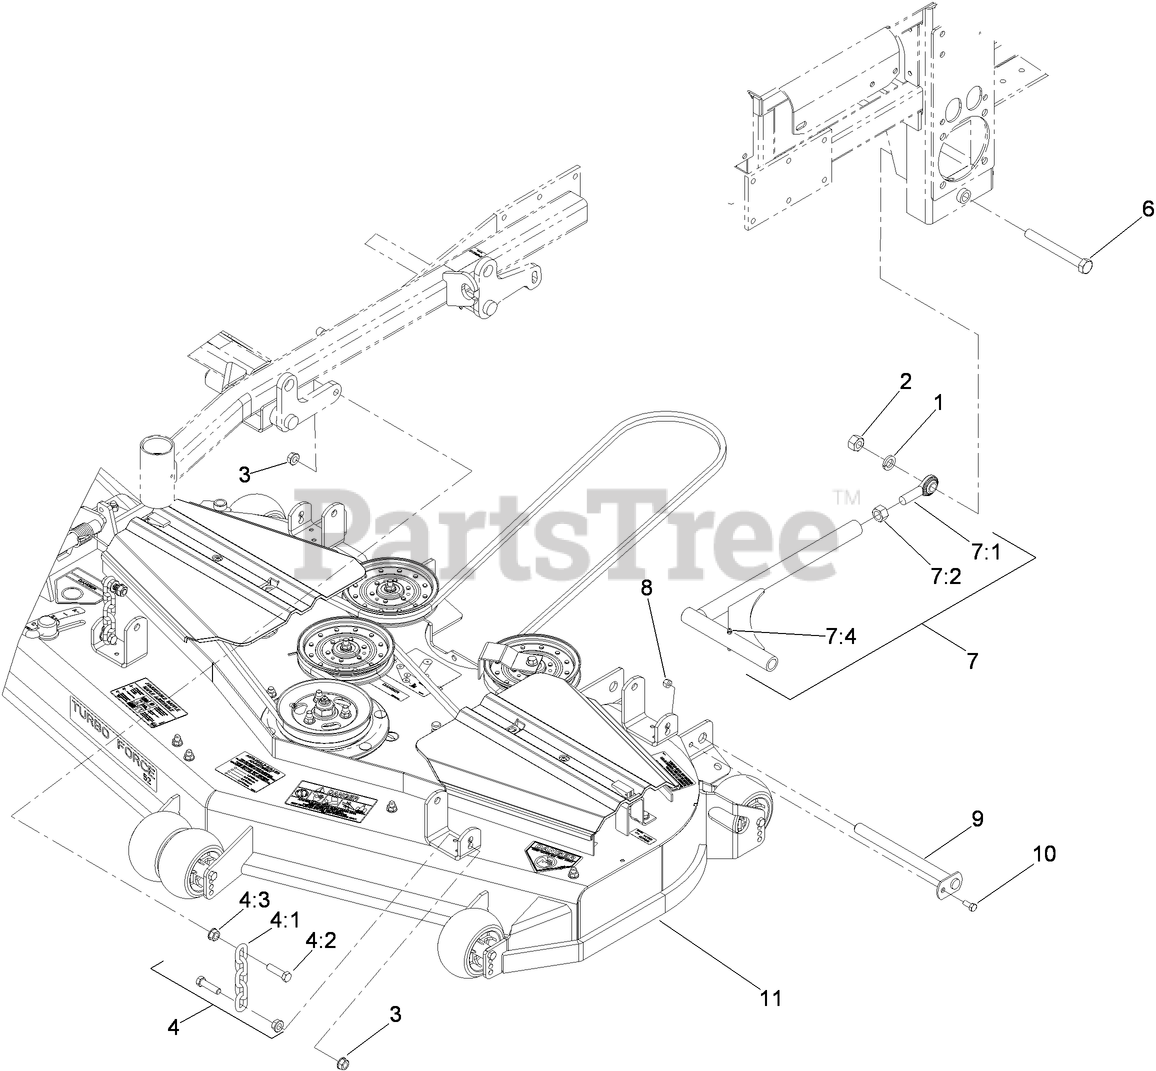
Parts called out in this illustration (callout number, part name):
1	WASHER-LOCK
2	NUT-HEX
3	NUT-HF
4	DECK CHAIN ASM
4:1	CHAIN-LIFT, DECK
4:2	SCREW-HH
4:3	NUT-HF
6	SCREW-HH
7	STRUT ASM
7:1	BALLJOINT-SPHERICAL
7:2	NUT-HEX
7:4	FITTING-GREASE
8	NUT-LOCK, NI
9	PIN-STRUT
10	SCREW-HH
11	DECK ASM
